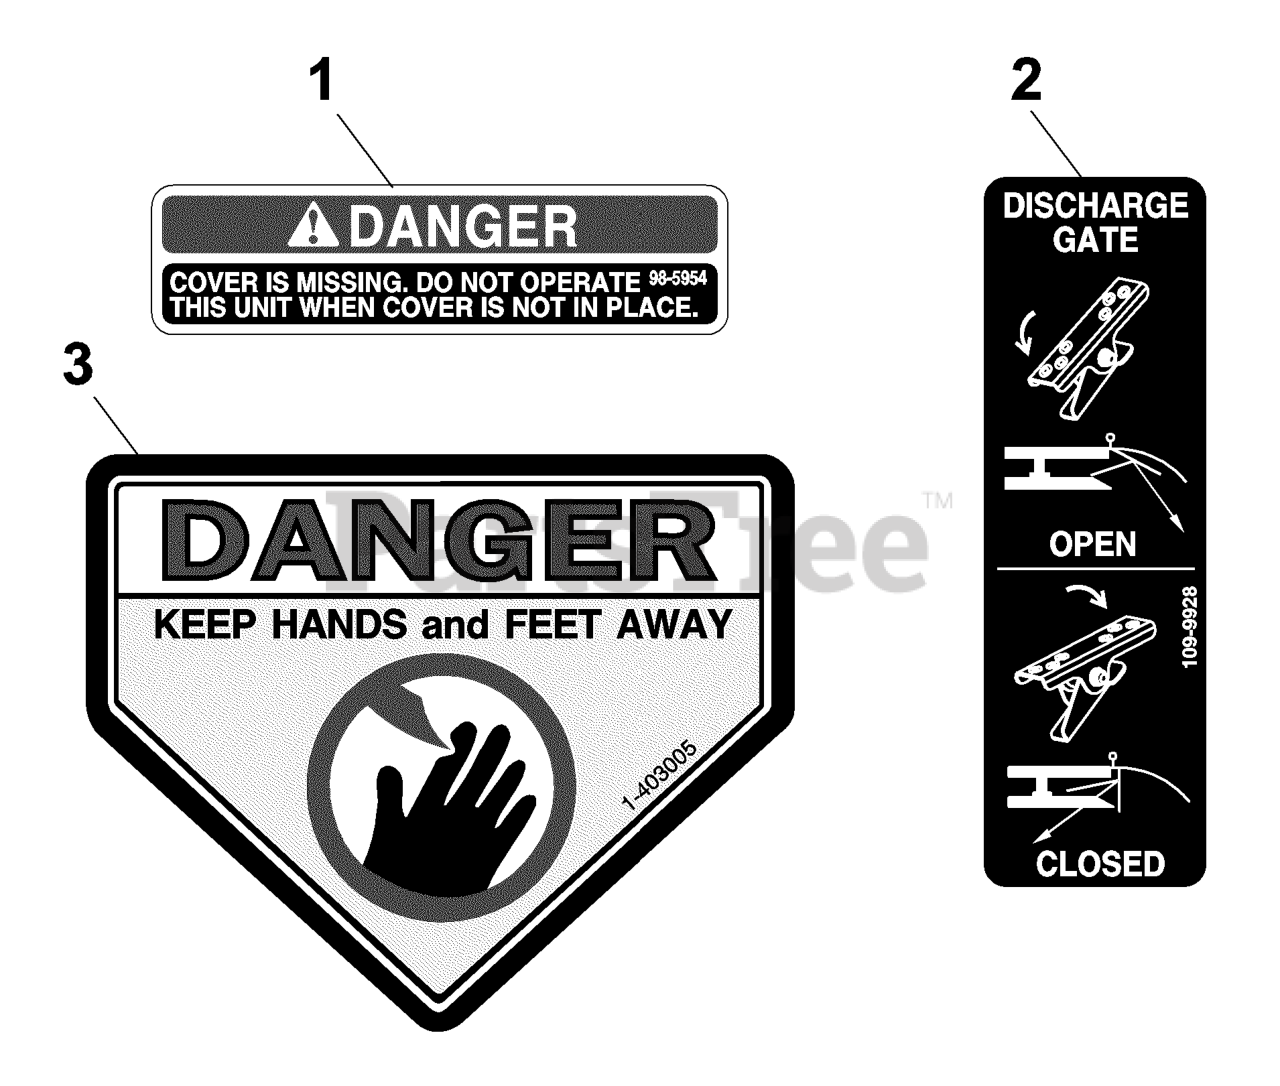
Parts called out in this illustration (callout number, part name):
1	Decal, Danger
2	Decal, Ocd02
3	Decal, Danger
